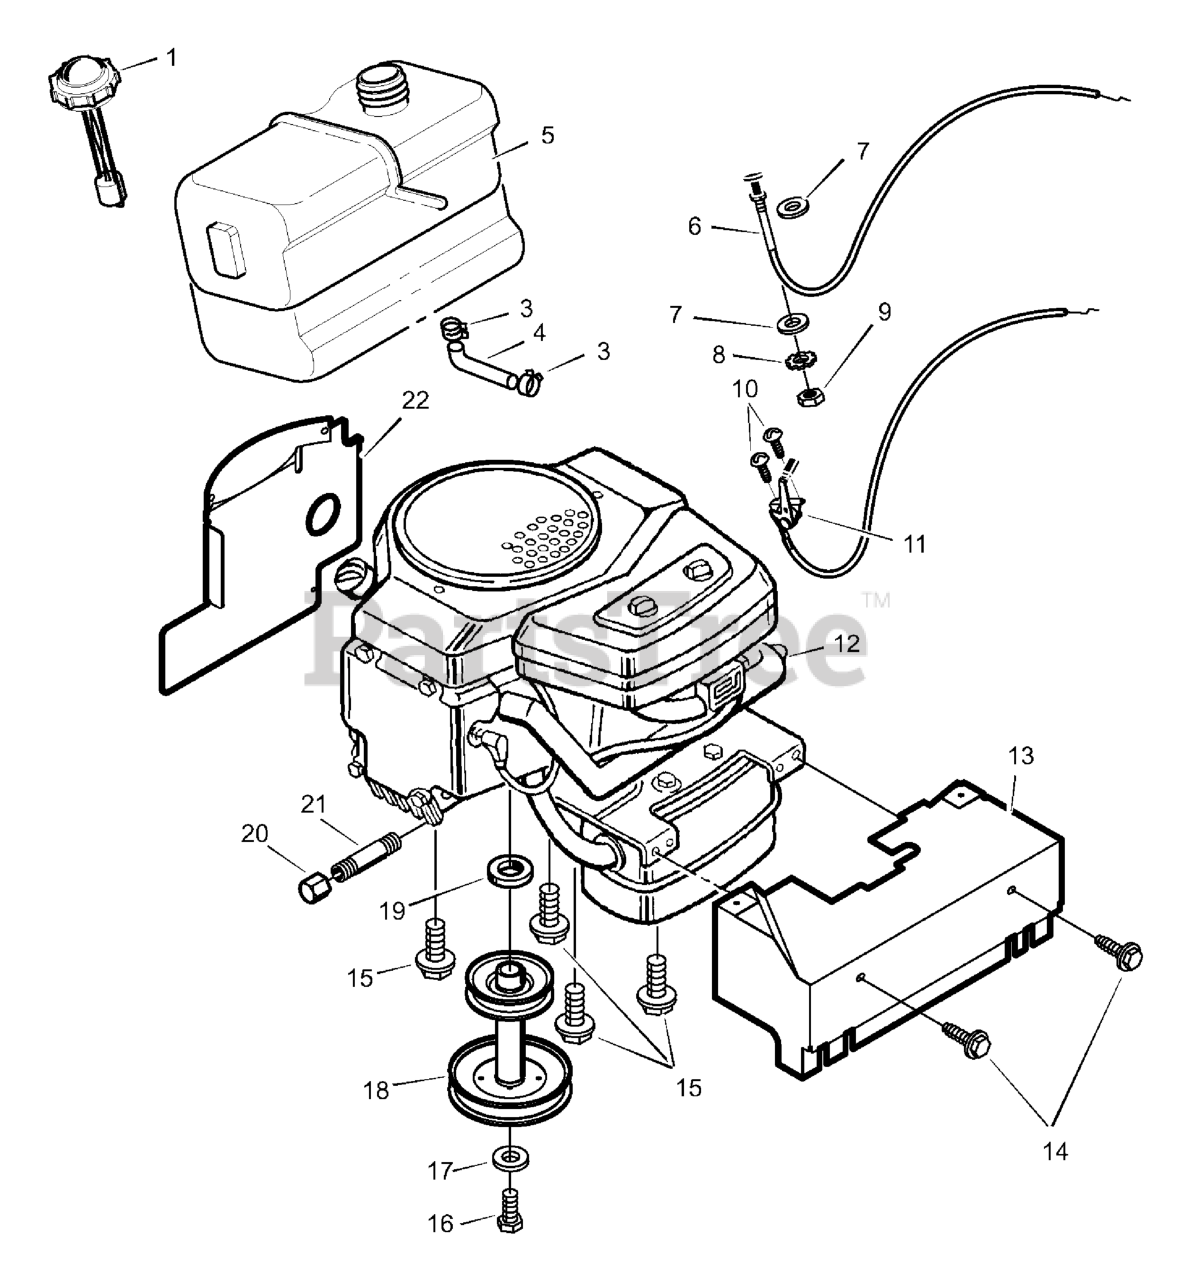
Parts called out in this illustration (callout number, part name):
1	Cap, Gas
3	Clamp
4	Line, Fuel
5	Tank, Fuel
6	Cable, Choke
7	Washer
8	Lockwasher
11	Control, Throttle
12	Engine *
13	Shield Assembly, Heat
15	Screw
18	Pulley, Stack
20	Cap, Oil Drain
21	Pipe, Oil Drain
22	Baffle, Rear Heat
